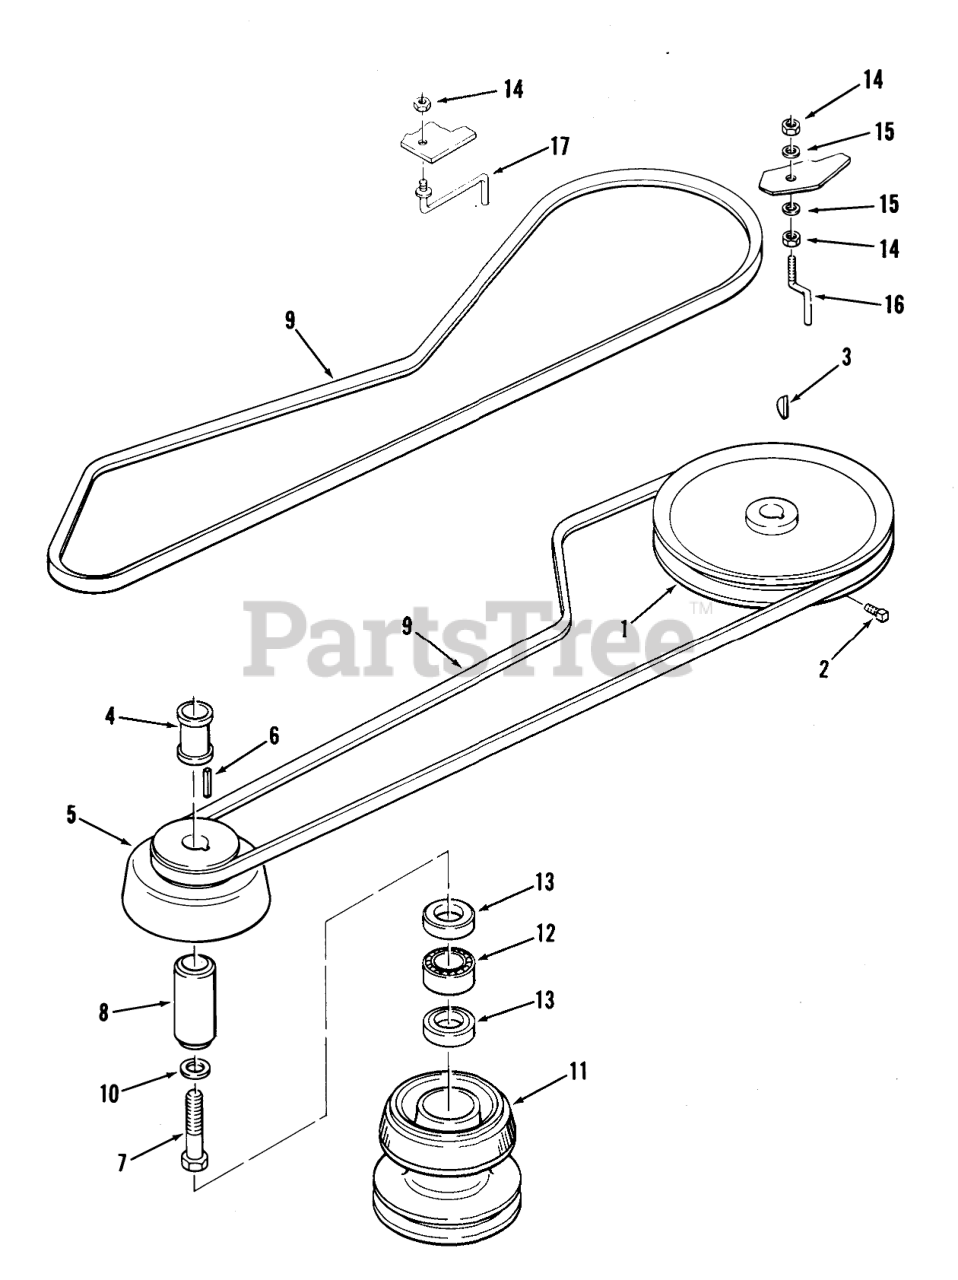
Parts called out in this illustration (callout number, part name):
1	PULLEY-TRANSMISSION
1	PULLEY-TRANS
2	Set Screw
3	HARD HI PRO KEY
3	KEY-HI-PRO
4	TUBE SPACER
5	PULLEY-ENGINE
7	HEX HD CAP SCREW
8	RACE BEARING
9	V-BELT
10	WASHER
11	Assy Pulley Mwr Dr
12	BRG-NEEDLE OPEN END
13	SEAL-OIL
14	Nut
15	WASHER 5/16 SAE
16	GUIDE-BELT
17	Belt Guide
